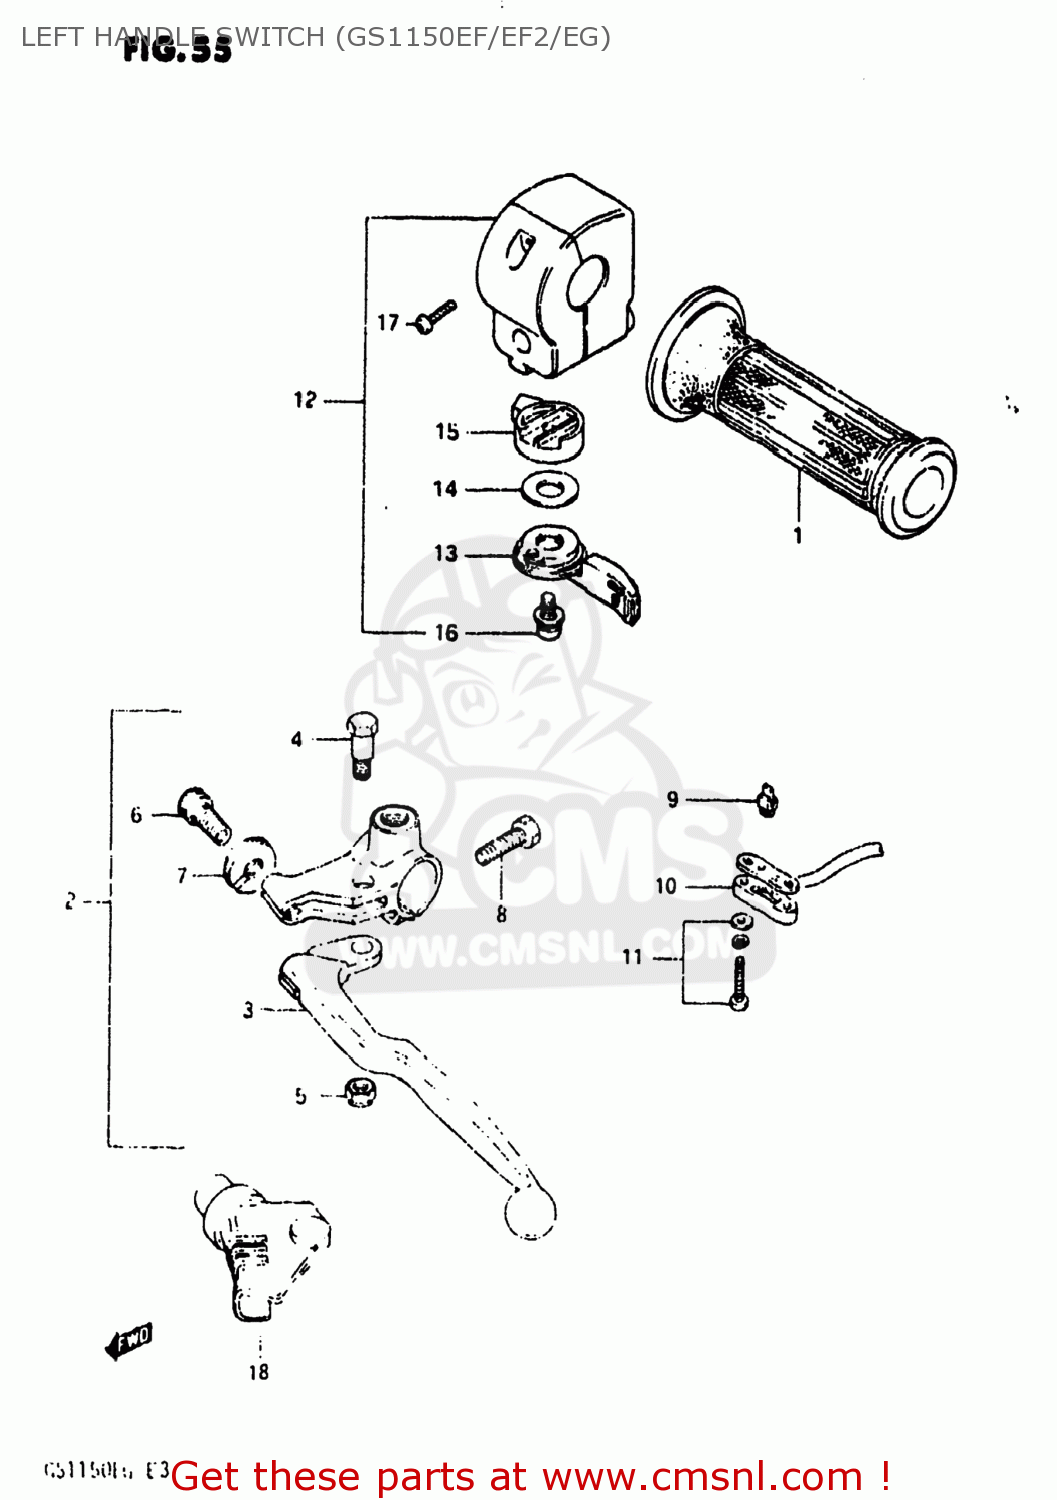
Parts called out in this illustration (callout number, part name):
1	GRIP,L
2	CLUTCH LEVER & SWITCH ASSY
3	LEVER,CLUTCH
4	BOLT,LEVER
5	NUT
6	ADJUSTER,CABLE
7	NUT,CABLE ADJUSTER
8	BOLT
9	CONTACT,SWITCH
10	COVER,FR BK TERMINAL BASE
11	SCREW
12	SWITCH ASSEMBLY,HANDLE,LEFT
13	LEVER,STARTER
14	WASHER,ADJUSTER
15	BODY,STARTER LEVER
16	SCREW,CHOKE LE
17	SCREW
18	COVER,CLUTCH LEVER
